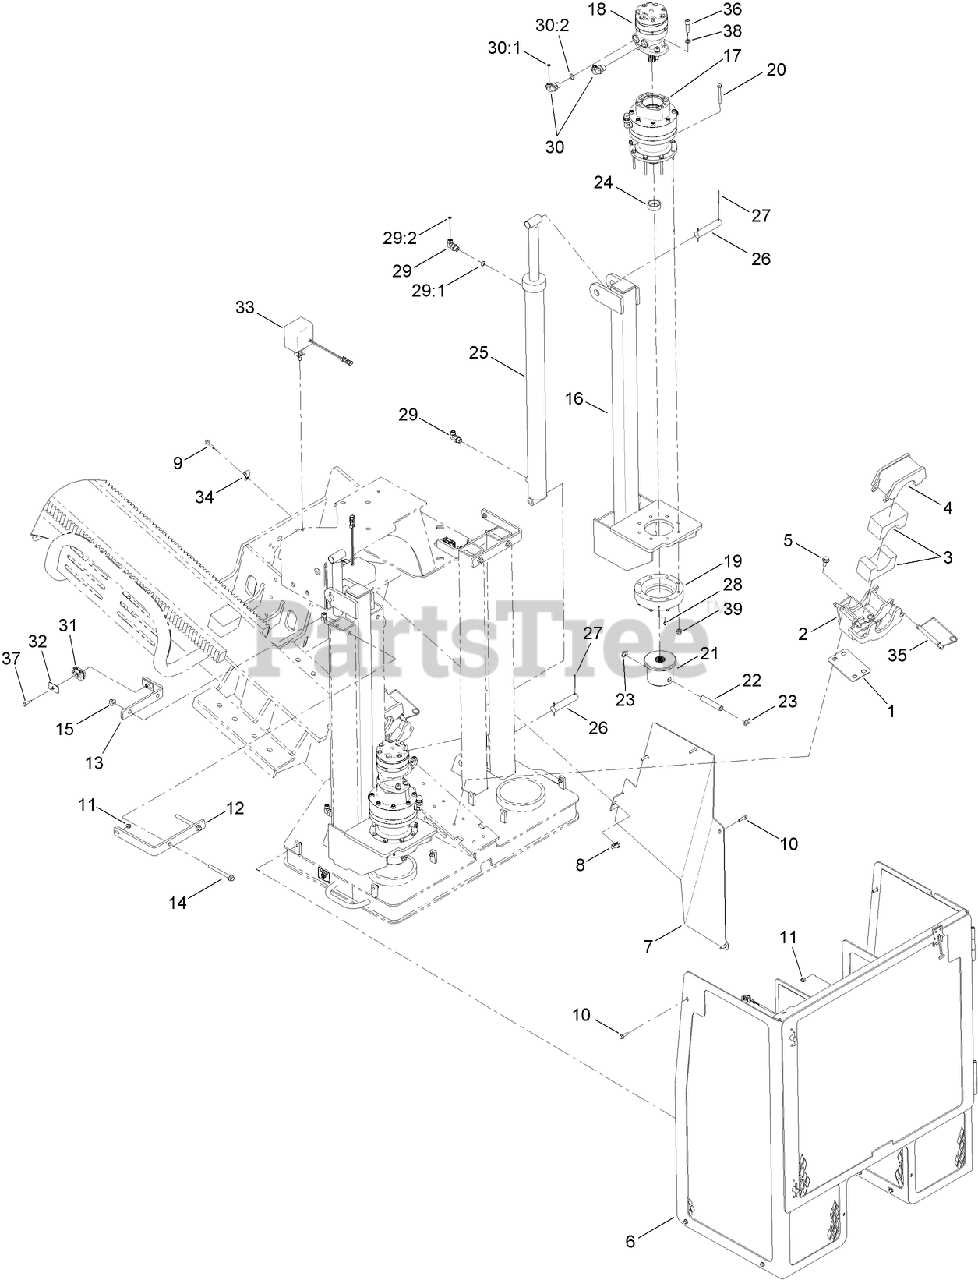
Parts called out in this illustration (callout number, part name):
1	PLATE-SHIM, BUSHING GUIDE
2	GUIDE-ROD, LOWER
3	BUSHING-GUIDE, ROD
4	GUIDE-ROD, UPPER
5	SCREW-HHF
6	STAKEDOWN CAGE ASM
7	PLATE-GUARD
9	SCREW-HHF
10	SCREW-HHF
11	NUT-LOCK, HHF
12	PLATE-MOUNT, STAKEDOWN
13	BRACKET ASM
14	SCREW-HHF
15	NUT-LOCK, HHF
16	STAKEDOWN
17	PLANETARY GEARBOX ASM
18	HYD MOTOR ASM
20	SCREW-HHF
21	COUPLER-AUGER DRIVE, STAKEDOWN
22	PIN-BAR, AUGER COUPLER
23	RING-RETAINING, E-TYPE
24	SPACER-TUBE
25	HYD CYLINDER ASM
26	PIN-BAR
27	PIN-COTTER
28	FITTING-GREASE
29	FITTING-HYD, 90 DEG
29:1	O-RING
29:2	O-RING
30	FITTING-ELBOW 90
30:1	O-RING
30:2	O-RING
31	CLAMP-HALF (SET OF 2)
32	PLATE-COVER, TWIN
33	LIGHT-WORK
34	R-CLAMP
35	PIN-LYNCH
36	SCREW-HSH
37	SCREW-HH
38	WASHER-LOCK
39	NUT-LOCK, NI
